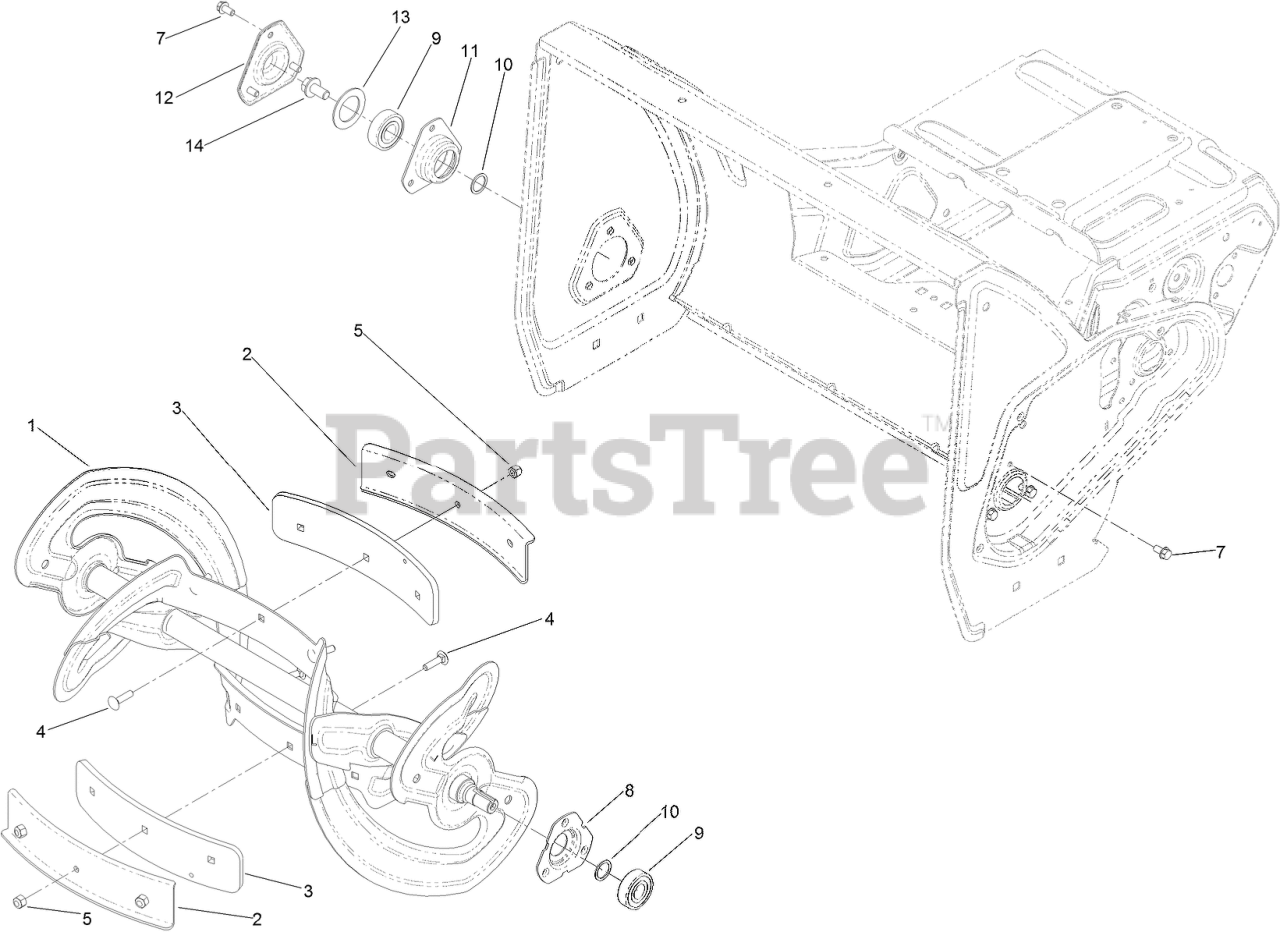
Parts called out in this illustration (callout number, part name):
1	ROTOR ASM
2	SUPPORT-CENTER, ROTOR
3	PADDLE-CENTER
4	SCREW-CARR
5	NUT-LOCK, NI
7	SCREW-HWH
8	FLANGE-BEARING
9	BEARING-BALL
10	WASHER-THRUST
11	BEARING-RETAINER
12	CAP-BEARING
13	WASHER-RUBBER
14	SCREW-HWH
